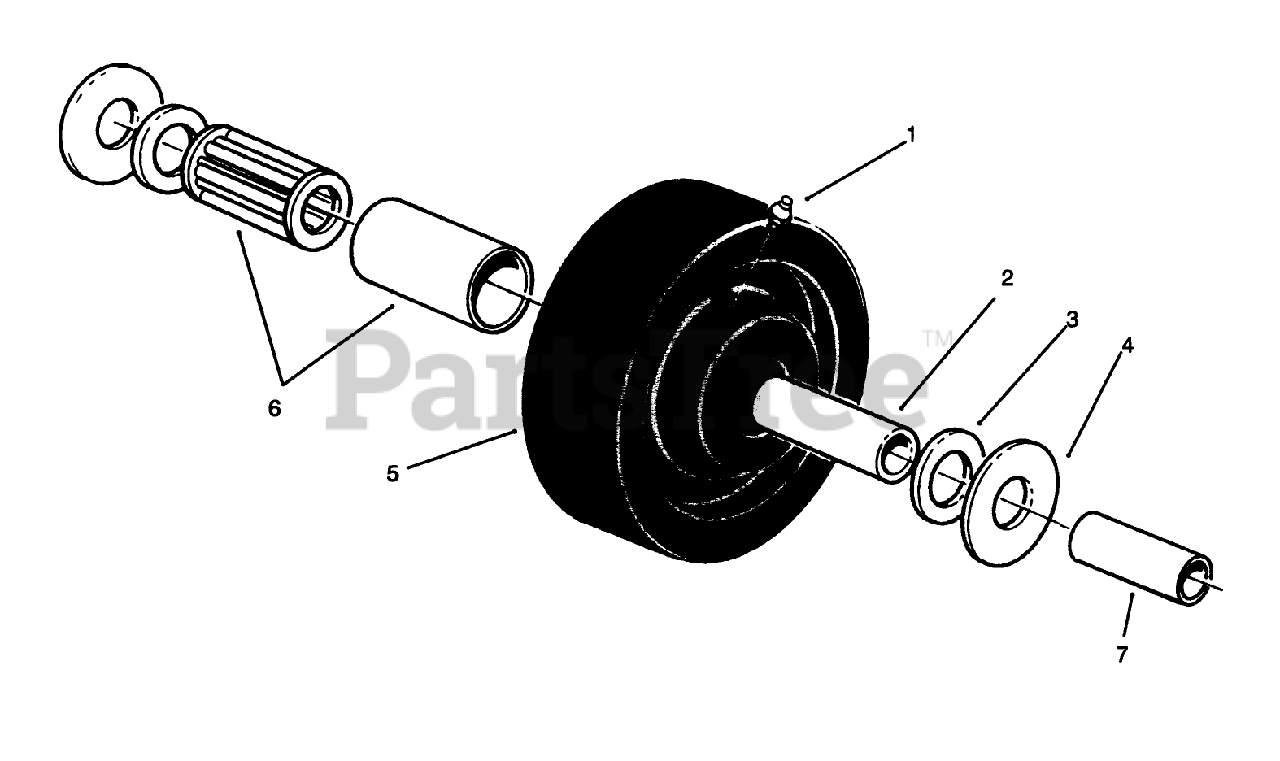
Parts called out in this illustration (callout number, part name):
1	Fitting-Grease
2	SPANNER BUSHING
3	BEARING RETAINER
4	THRUST WASHER
5	WHEEL
6	ROLLER BEARING
7	SPANNER-TIRE
